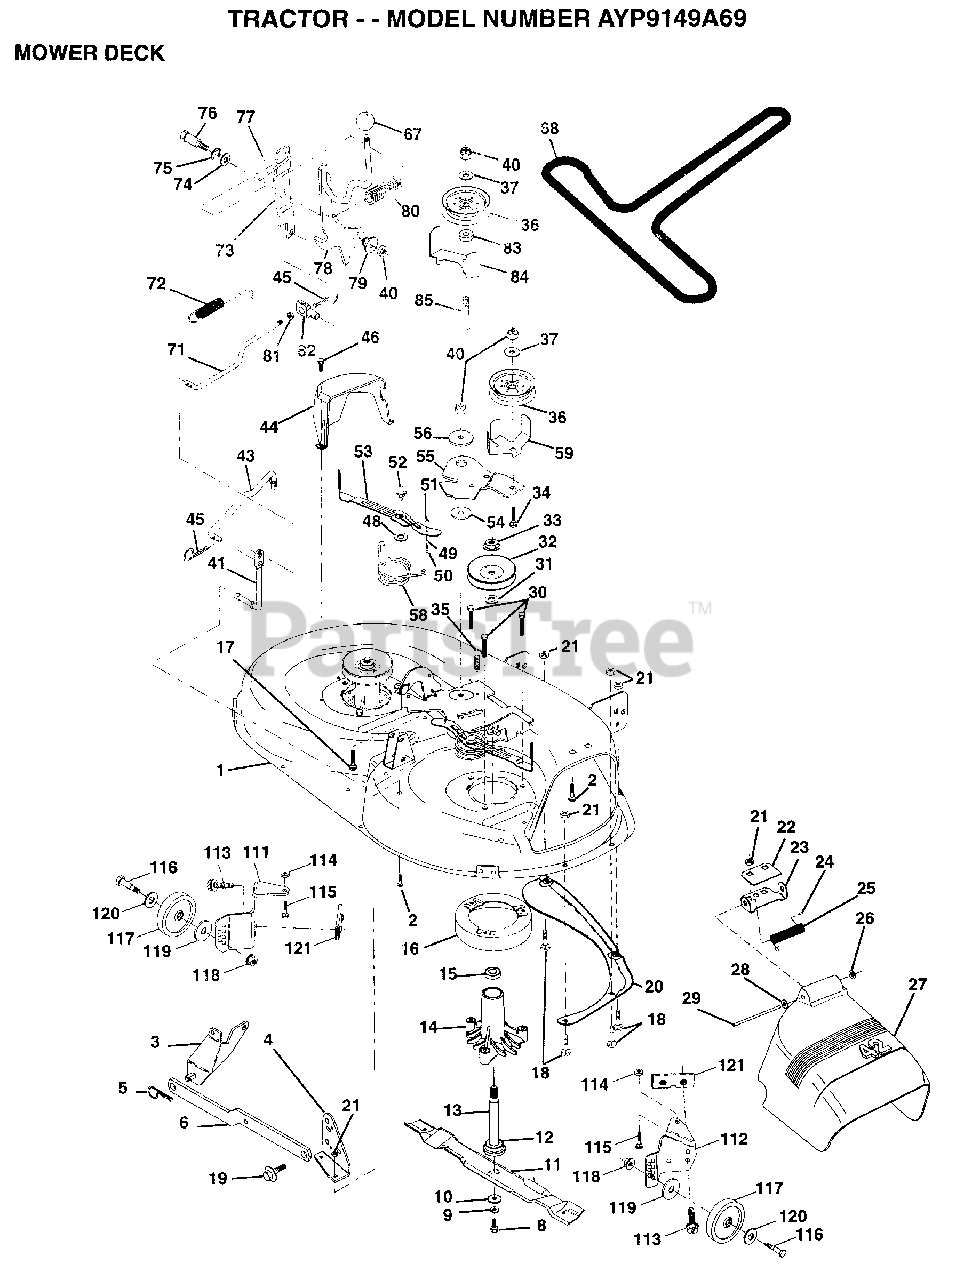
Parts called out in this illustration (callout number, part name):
1	DECK.WELD.42.
2	BOLT
3	BRKT ASM SWAY BAR
4	BRKT DECK SW BAR
8	BLADE BOLT
10	WASHER.HARD.BLADE
11	"BLADE.42"" MULCHER"
12	BEARING.BALL
14	HSG ASM MANDREL
14	BOLT RDHD 3/8-16
15	BEARING
16	STRIPPER RND MWR
18	BOLT
19	BOLT SHD 5/16-18
22	STIFFENER BRKT
23	DEFLECTOR BRKT
24	CAP-SLEEVE LT
25	SPRING TORSION
26	NUT PUSH M
27	DEFLECTOR.SHIELD
28	WASHER
29	HINGE ROD
31	WASHER
34	BOLT
35	XMAS TREE FASTNER
36	FLAT IDLER PULLEY
39	WASHER
41	PIVOT ROD
43	ROD CLUTCH W/NIBS
44	GUARD MAND LH BLK
45	RETAINER M
46	SCREW.1/4-20X5/8
48	HARD SMALL WASHER
50	SHOULDER BOLT
51	LOCKNUT
52	BOLT.SHLD.5/16-18
53	BRAKE PAD ARM ASM
54	HARDENED WASHER
56	SPACER RETAINER
58	SPRING TORSN BRAK
59	GUARD IDLER TUV
67	KNOB T (1/2-HOLE)
68	BELT.V.T-PATH
71	ROD CLUTCH 38/42
72	RETURN SPRING
73	CLUTCH ARM SECOND
74	WASHER
75	RING
76	SHOULDER BOLT
77	SPRING KEEPER
78	LEVER ASM CLT PRM
79	BUSHING
81	NUT
82	TRUNION ADJ
83	WASHER
85	BOLT RDHD 3/8-16
113	SCREW
116	BOLT M
117	WHEEL.GAGE.BLK.PL
118	LOCKNUT
119	WASHER
120	WASHER
121	BRACKET.EXTRD.GWL
